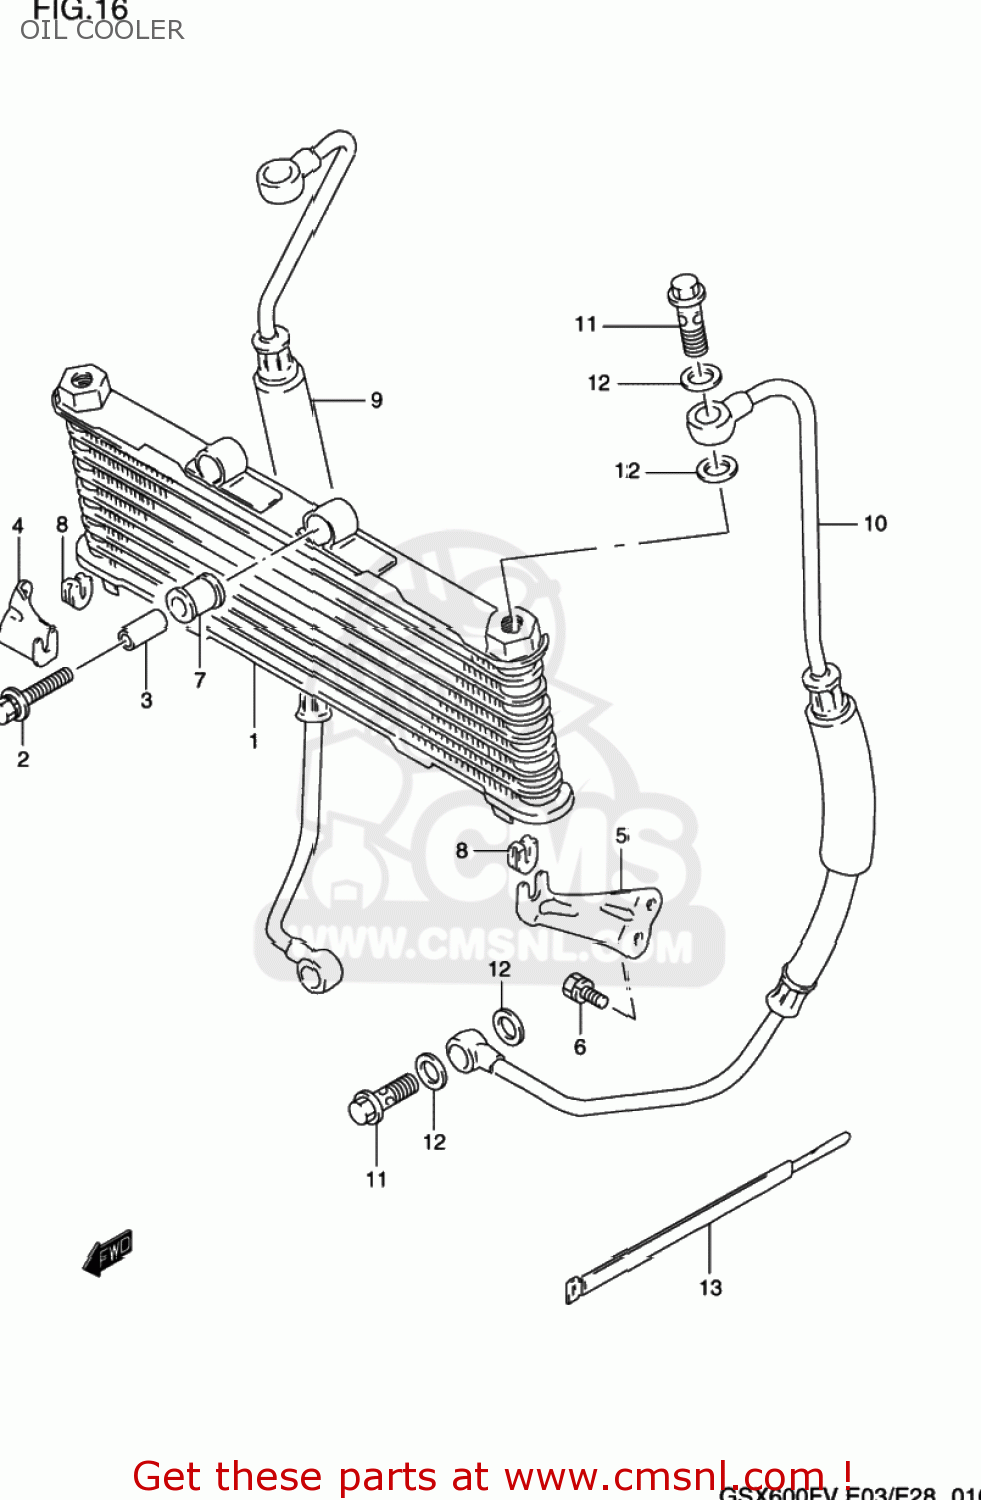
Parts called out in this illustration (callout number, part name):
1	COOLER ASSEMBLY,OIL
2	BOLT(8X40)
3	SPACER(8.5X12X25)
4	BRACKET,OIL COOLER,R
5	BRACKET,OIL COOLER,L
6	BOLT
7	CUSHION,OIL COOLER NO.1
8	CUSHION,OIL COOLER NO.2
9	HOSE,OIL COOLER,RIGHT
10	HOSE,OIL COOLER,LEFT
11	BOLT UNION
12	GASKET(16X22X2) (NAS)
13	CLAMP(L:235)
